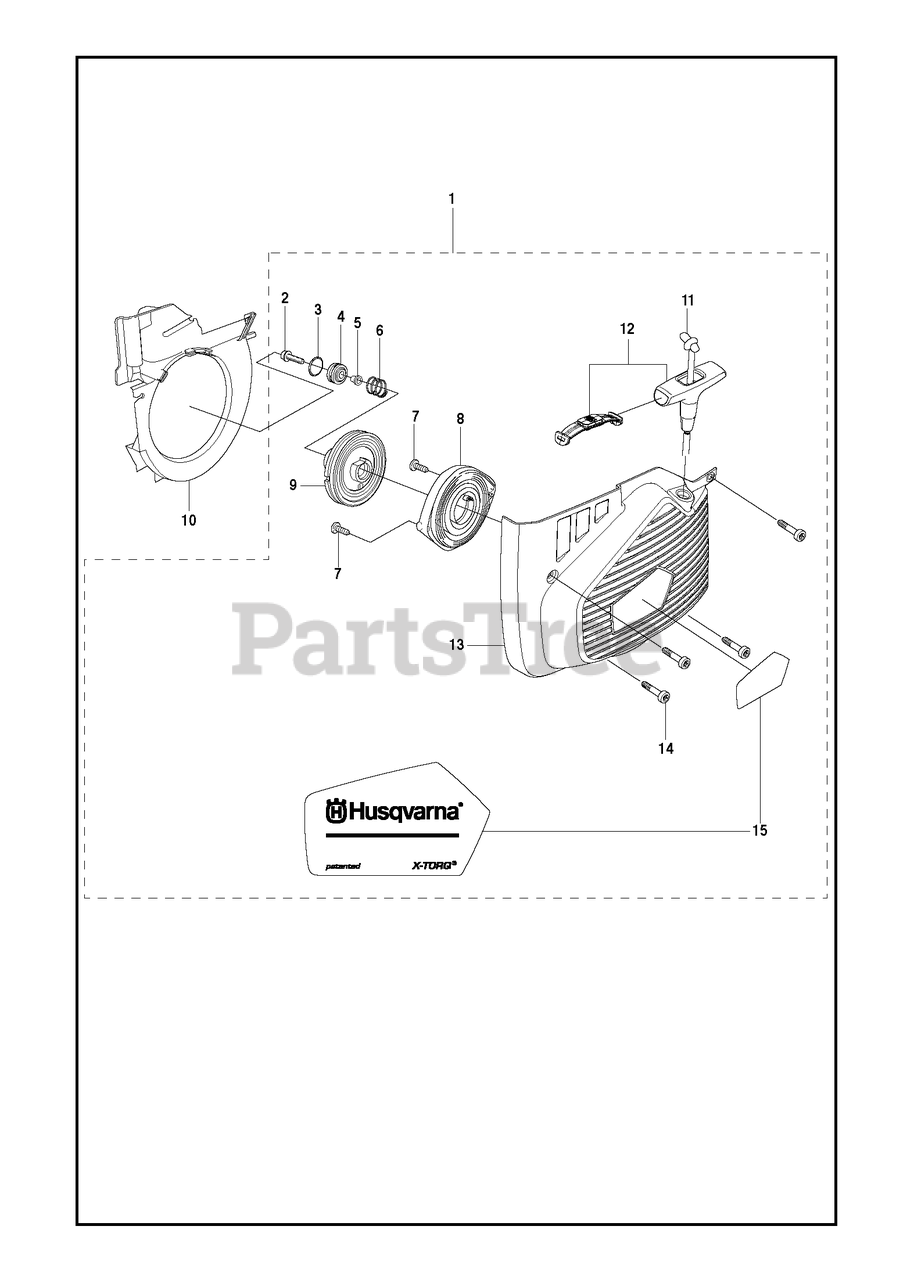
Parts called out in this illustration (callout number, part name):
1	STARTER ASSY
2	SCREW IHSCT
4	GROMMET
5	SPACING SLEEVE
6	COMPRESSION SPRING
7	SCREW CITXPANT
8	RECOIL SPRING
9	STARTER PULLEY
10	AIR CONDUCTOR
11	STARTER CORD
12	STARTER HANDLE ASSY
13	STARTER COVER
14	SCREW ITXSCM
